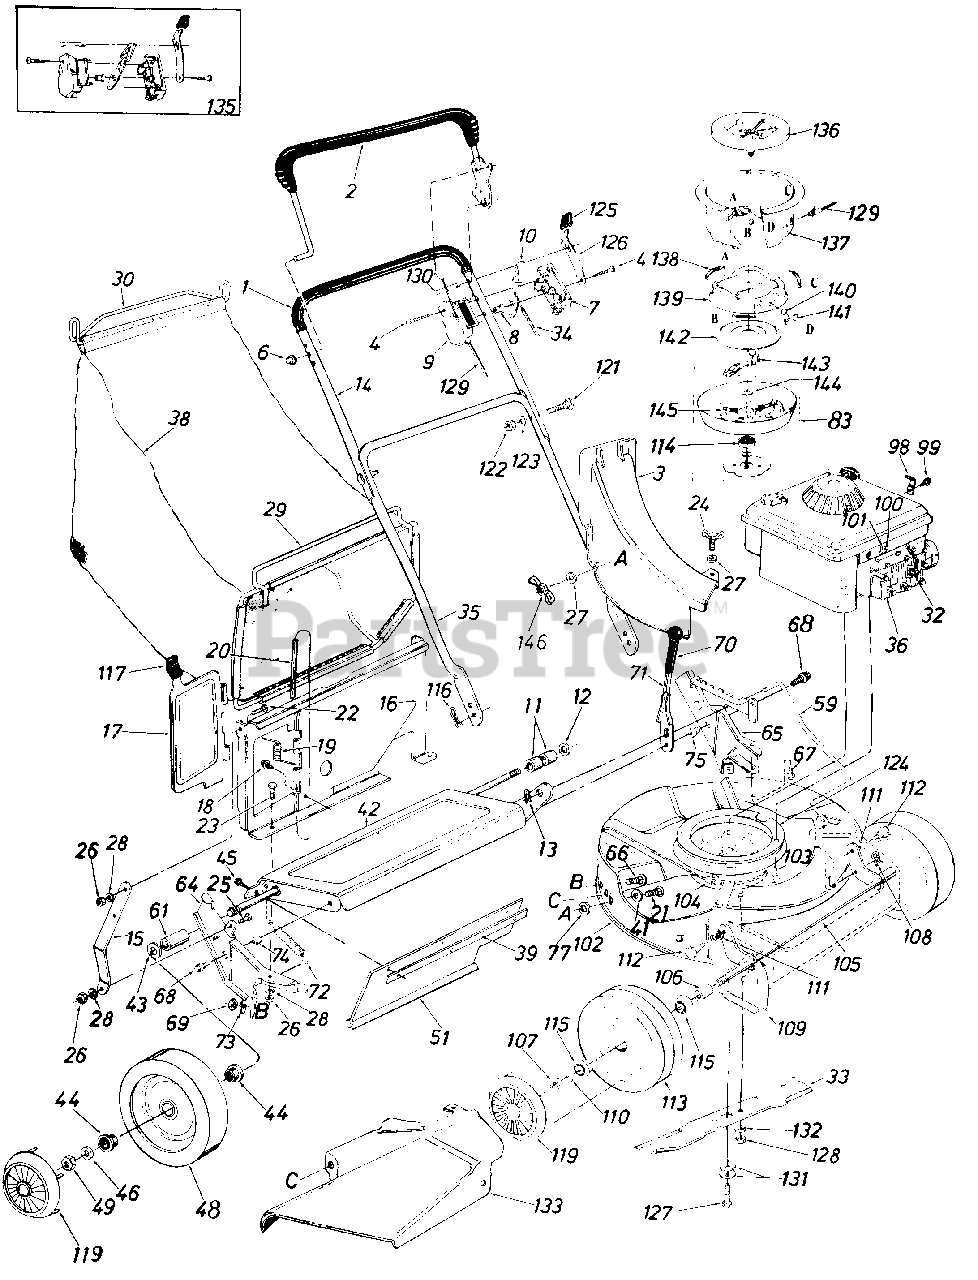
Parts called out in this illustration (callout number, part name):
2	Control Handle Ass'y.-L.H.
3	Top Discharge Chute Ass'y.
4	Truss Mach. Scr. #12 x 1.50" Lg.
6	Cap Speed Nut .31 Dia.
7	Control Panel Half
8	Control Disc Pin
9	Clutch Panel Half
10	Throttle Control Lever
11	Spacer .526" I.D. x .690" O.D. x .640" Lg.
12	Fl-Wash. .531" I.D. x .930" O.D.
13	Intern. Cotter Pin 5/16" Dia.
14	Upper Handle-Chrome
15	Panel Support Brkt.
16	Top Catcher Panel
17	Top Door
18	Hex "B" Tap Scr. #10 x .38" Lg.
19	Torsion Spring .20" I.D. x 1.14" Lg.
20	Pivot Pin .187" Dia. x 7.25" Lg.
21	Carriage Bolt 1/4-20 x .62" Lg.*
22	Truss Mach. Scr. 1/4 x .50" Lg.
23	Hex Bolt 1/4-20 x .50" Lg.
24	Wing Bolt 1/4-20 x .62" Lg.
25	Hex Bolt 1/4-20 x .62" Lg.
26	Hex Nut 1/4-20 Thd.
27	Fl-Wash. .280" I.D. x .620" O.D.
28	L-Wash. 1/4" I.D.
29	Front Grass Catcher Frame
30	Grass Catcher Handle
32	Spark Plug Insulator
33	21" Blade
34	Throttle Control Wire 58.0" Lg.
35	Lower Handle-Chrome
36	Engine
38	21" Top Discharge Grass Bag
39	Retaining Strip
41	Fl-Wash. .344" I.D. x .62" O.D.
42	Rear Axle Ass'y.
43	Fl-Wash. .531" I.D. x .930" O.D.
44	Flange Ball Bearing 1/2" I.D.
45	Hex AB-Tap Scr. 1/4 x .62" Lg.
46	Fl-Wash. .531" I.D. x .930" O.D.
48	Rear Wheel Ass'y.-Comp. 8 x 1.75
49	Hex L-Nut 1/2-20 Thd.
51	Rear Flap 3.75" x 17.30" Lg.
59	Height Adj. Rod 1.50" x 19.42" Lg.
61	Spacer. 51" I.D. x .69" O.D. x.690" Lg.
64	R.H. Handle Wheel Brkt. Ass'y.
65	L.H. Handle Wheel Brkt. Ass'y.
66	Carriage Bolt 5/16-18 x .62" Lg.*
67	Hex Wash. Hd. B-Tap Scr. 5/16-18
68	Hex Wash. Hd. TT-Tap Scr. 3/8-1 6
69	Hex Nut 5/16-18 Thd.
71	Height Adj. Lever 1.25 x 8.5" Lg.
72	Extension Spring .50" O.D. x 3.80" Lg.
73	Bell-Wash. .345" I.D. x .88" O.D.
74	Spacer.385" I.D. x .502" O.D. x .270" Lg.
75	Shld. Spacer. 500" Dia. x .100
77	Bolt Retainer 1/4 x .50" O.D.
83	Clutch Blade Housing Ass'y.
98	Throttle Control Cable Clip
99	Hex B-Tap Scr. #10 x .38" Lg.
100	Hex Sems Bolt #10-32 x 1.62" Lg.
101	Casing Clamp
104	Speed Nut 1/4-20 U-Type
105	Front Axle Ass'y.
106	Sleeve .526" I.D. x .690" O.D. x .880" Lg.
107	Hex L-Nut 1/2-20 Thd.
108	Intern. Cotter Pin 5/16" Dia.
109	Extension Spring .50" O.D. x 3.20" Lg.
110	Fl-Wash. .531" I.D. x .930" O.D.
111	Intern. L-Wash. 3/8 x .56" O.D.
112	Shld. Bolt.623" Dia. x.425
113	Front-Wheel Ass'y. Comp. 7 x 1.75
114	Ball Brg. .69" I.D. x 1.574"
115	Flanae Ball Bearina 1/2" I.D.
116	Intern. Cotter Pin 5/16" Dia.
117	Door Grip x 2.5
119	Hub Cap-Plastic
121	Curved Carr. Bolt 5/16-18 x 1.38" Lg.
122	Hex Nut 5/16-18 Thd.
123	L-Wash. 5/16" I.D.
124	Blade Brake Clutch Comp.
125	Spring Lever Knob
126	Lockout Spring
127	Hex Cent. L-Bolt 3/8-24 x 2.00" (Grade 8)
128	Hex Nut 3/8-24 Thd. (Grade 8)
129	BBC Clutch Cable x 46.0"
130	Lock Pin .314" Dia. x 1.75" Lg.
131	Bell-Wash. .400" I.D. x .88" O.D.
132	L-Wash. 3/8" I.D.
133	Side Chute Deflector
135	Kit-Control Housing Comp.
136	Fan Adapter
137	Clutch Housing
138	Extension Spring .35 O.D. x 1.75" Lg.
139	Brake Cup Cone
140	Steel Ball .500" Dia.
141	Ball Block
142	Clutching Cone
143	Hex Tap L-Scr. 1/4-20 x .75" Lg.
144	Fl-Wash. .690ll I.D. x 1.060 O.D.
145	Compression Spring .35Ir O.D. x 2.00ll Lg.
146	Wing Nut
